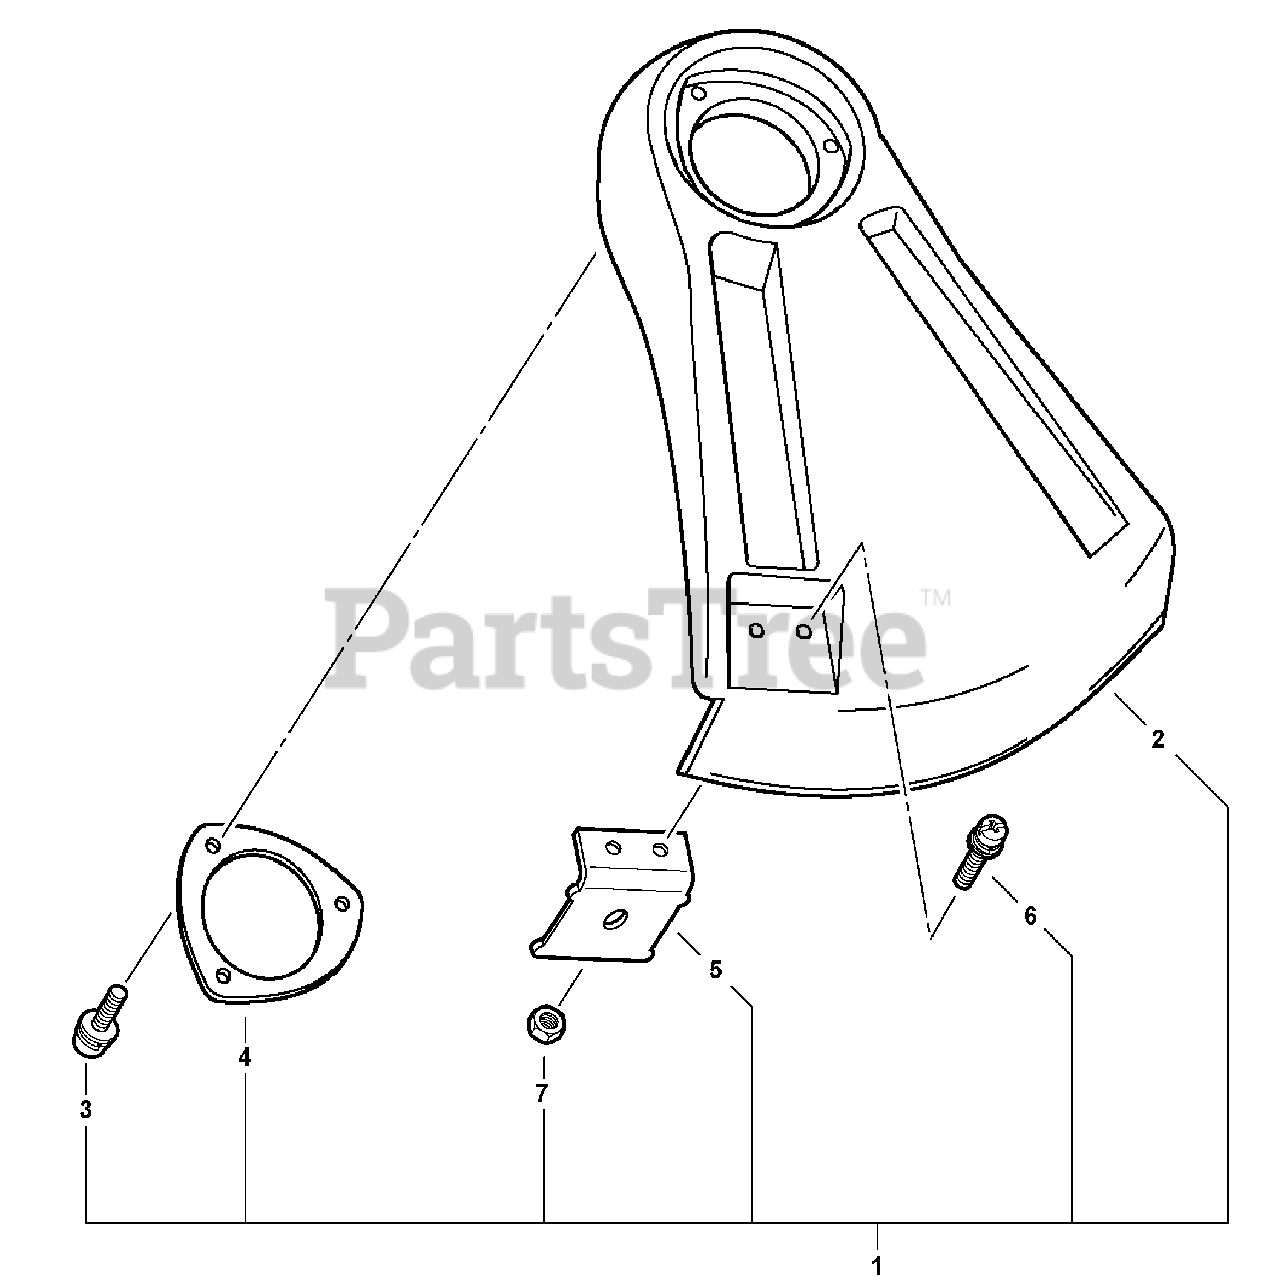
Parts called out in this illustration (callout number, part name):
1	Plastic Shield Kit
2	Shield - Plastic
3	Screw 5x20
4	Flange, Shield
5	Cutter, Line
6	Screw 5x16
